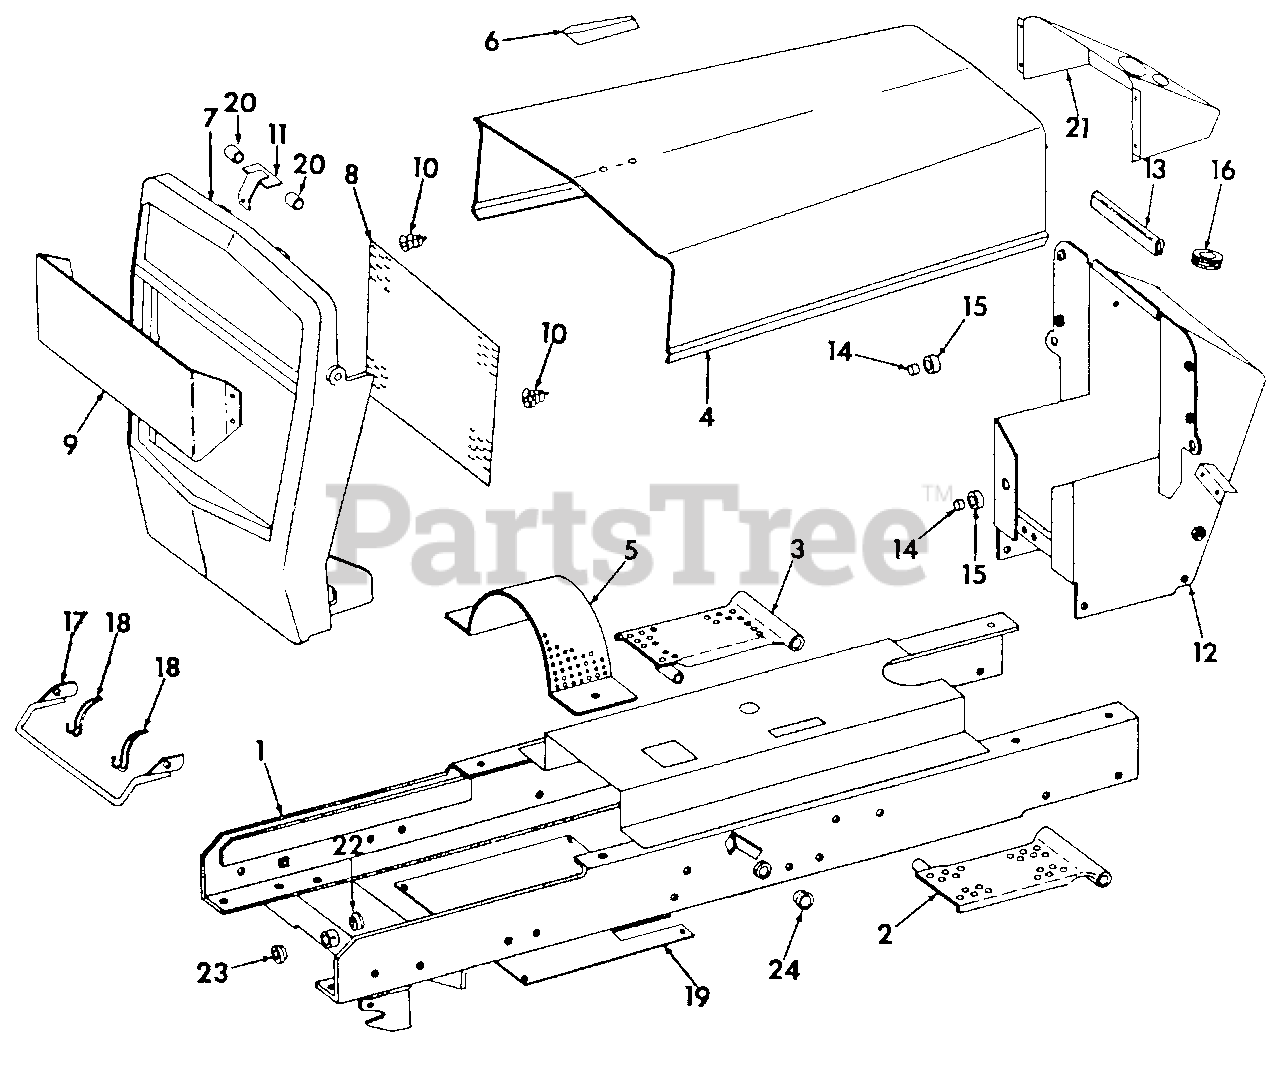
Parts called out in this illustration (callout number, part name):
1	Frame Assy
2	Support Assy, Foot LH
3	Support Assy, Foot RH
4	Hood Assy
5	Shield, Clutch
6	Product Graphic, Hood Ornament
7	Housing, Grille
9	Strip Assy, Grille Panel
10	Spring, Hold Down
11	Not used in this application
12	Pedestal Assy
13	Bumper, Hood
14	Not used in this application
15	Not used in this application
16	Grommet, Instrument Panel
17	Hitch Assy, Quick
18	Spring, Latch
19	Sheet, Bottom Clutch Shield
20	Pad, Hood Bumper
21	Panel, Instrument
22	Washer, Front Axle Pivot Pin Rear
23	Bracket, Front Axle Pivot Pin Shaft
24	Bearing, Clutch Pedal Shaft
